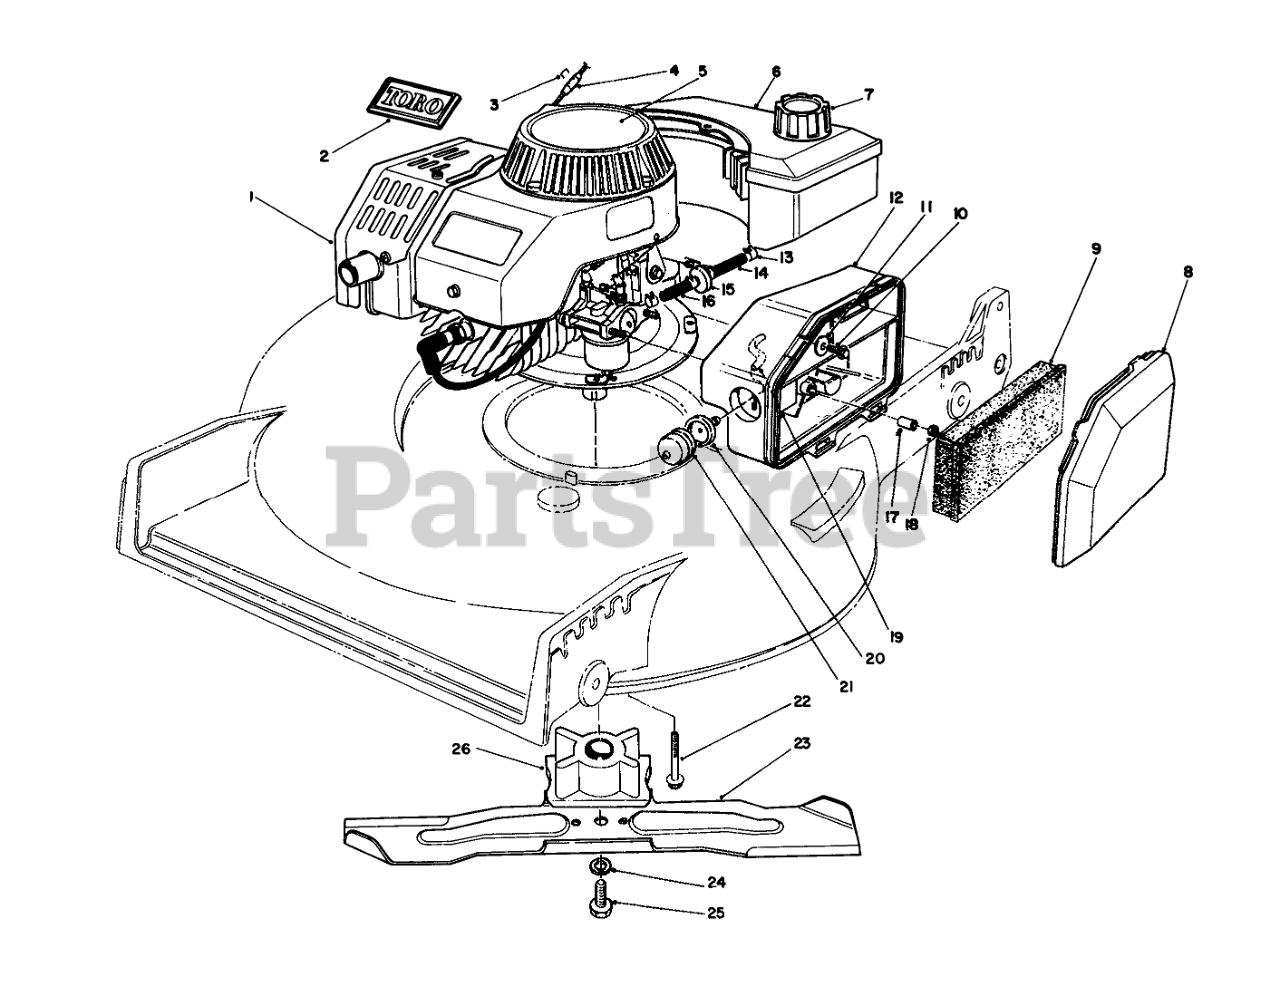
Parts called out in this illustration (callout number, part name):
1	Engine
2	TORO LOGO PLT
3	Staple
5	DECAL- 2 CYC RECOIL
6	Gas Tank Assembly
7	GAS CAP ASM
8	COVER-AIR CLEANER
9	ELEMENT-AIR CLEANER
10	SCREW-HH
11	WASHER-FLAT
12	BODY-AIR CLEANER
13	CLAMP-FUEL LINE
14	HOSE-FUEL
15	FILTER-FUEL
16	HOSE-FUEL
17	SPACER
19	HOSE-PRIMER
20	BODY-PRIMER
21	Bulb Primer
22	SCREW-HHF
23	BLADE-21in
24	WASHER-LOCK
25	SCREW-BLADE
26	BLADE RETAINER
